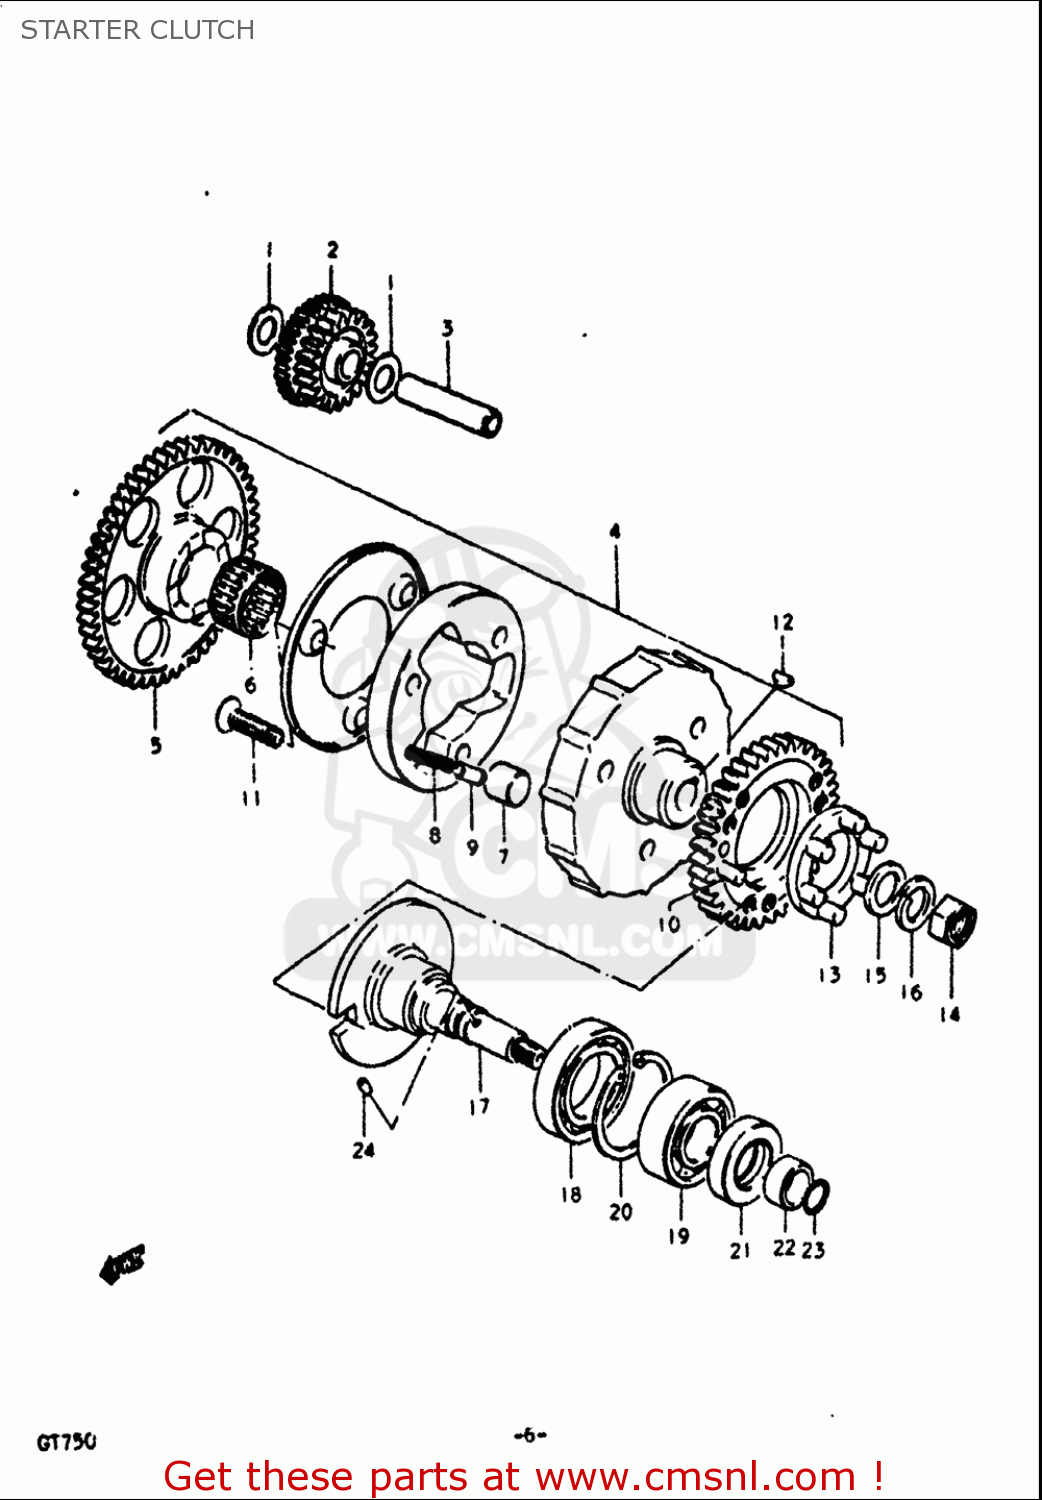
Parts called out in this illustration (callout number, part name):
1	WASHER(13.3X25X0.85)
3	PIN(7.4X13X56)
6	BEARING(25X29X9.9)
7	ROLLER(15X13)
8	SPRING
9	PIECE,PUSH
10	PIN
11	SCREW
12	KEY
14	NUT
15	WASHER
16	WASHER,LOCK
19	BEARING
20	CIRCLIP
21	SEAL,OIL(20X35X7)
23	O RING(D:1.3,ID:11.6)
24	PIN
